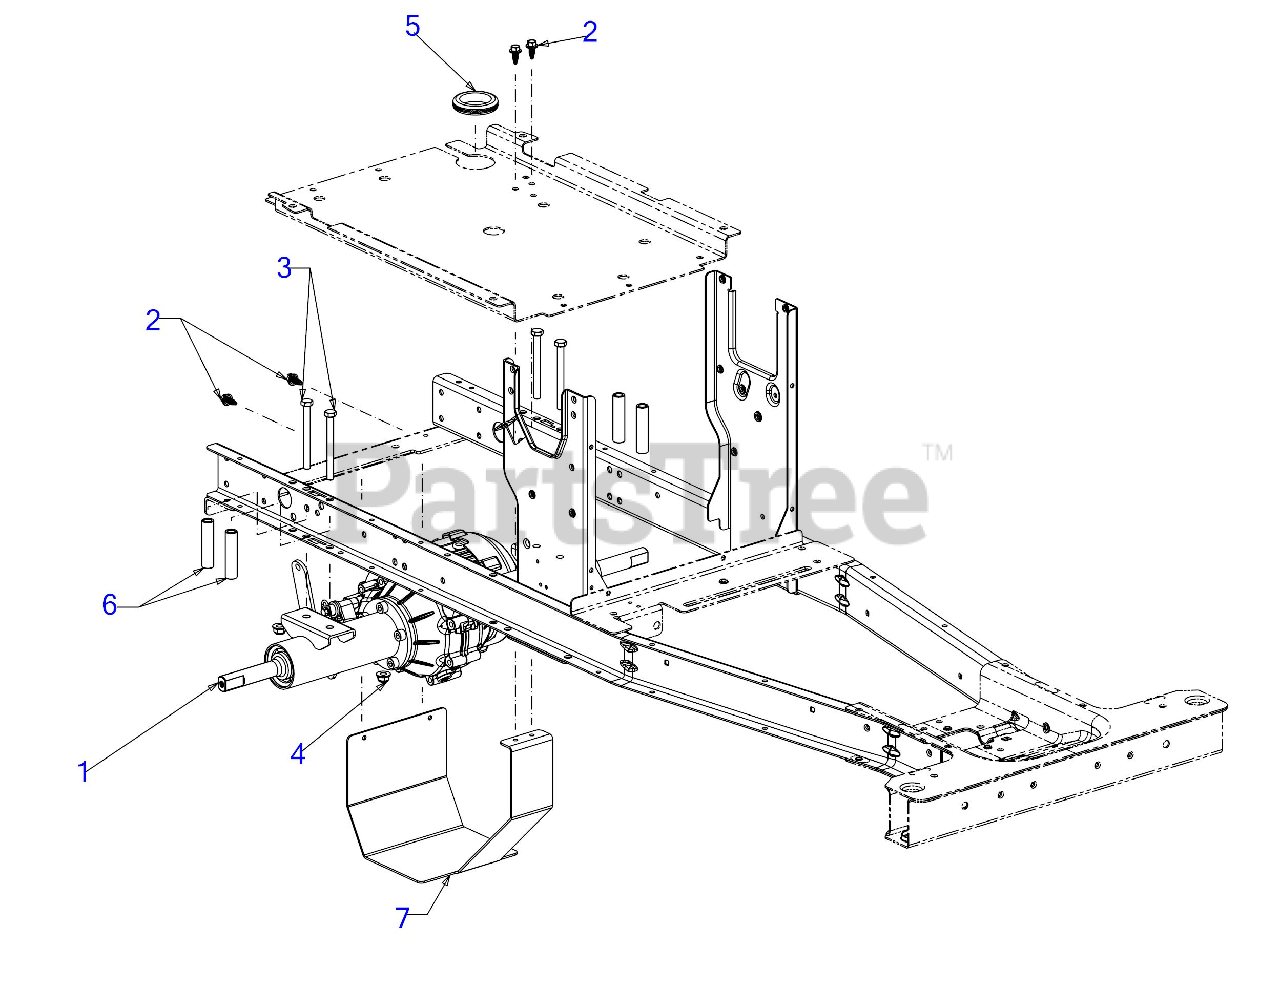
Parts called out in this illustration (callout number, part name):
1	TRANSMISSION ASSEMBLY
2	SCREW 1/4-20X.625
3	SCREW 5/16-18 x 3.25 GR5
4	FLANGE LOCK NUT 5/16-18
5	GROMMET (1.50 X 1.75 X 0.06)
6	SPACER (.35 X .55 X 2.345)
